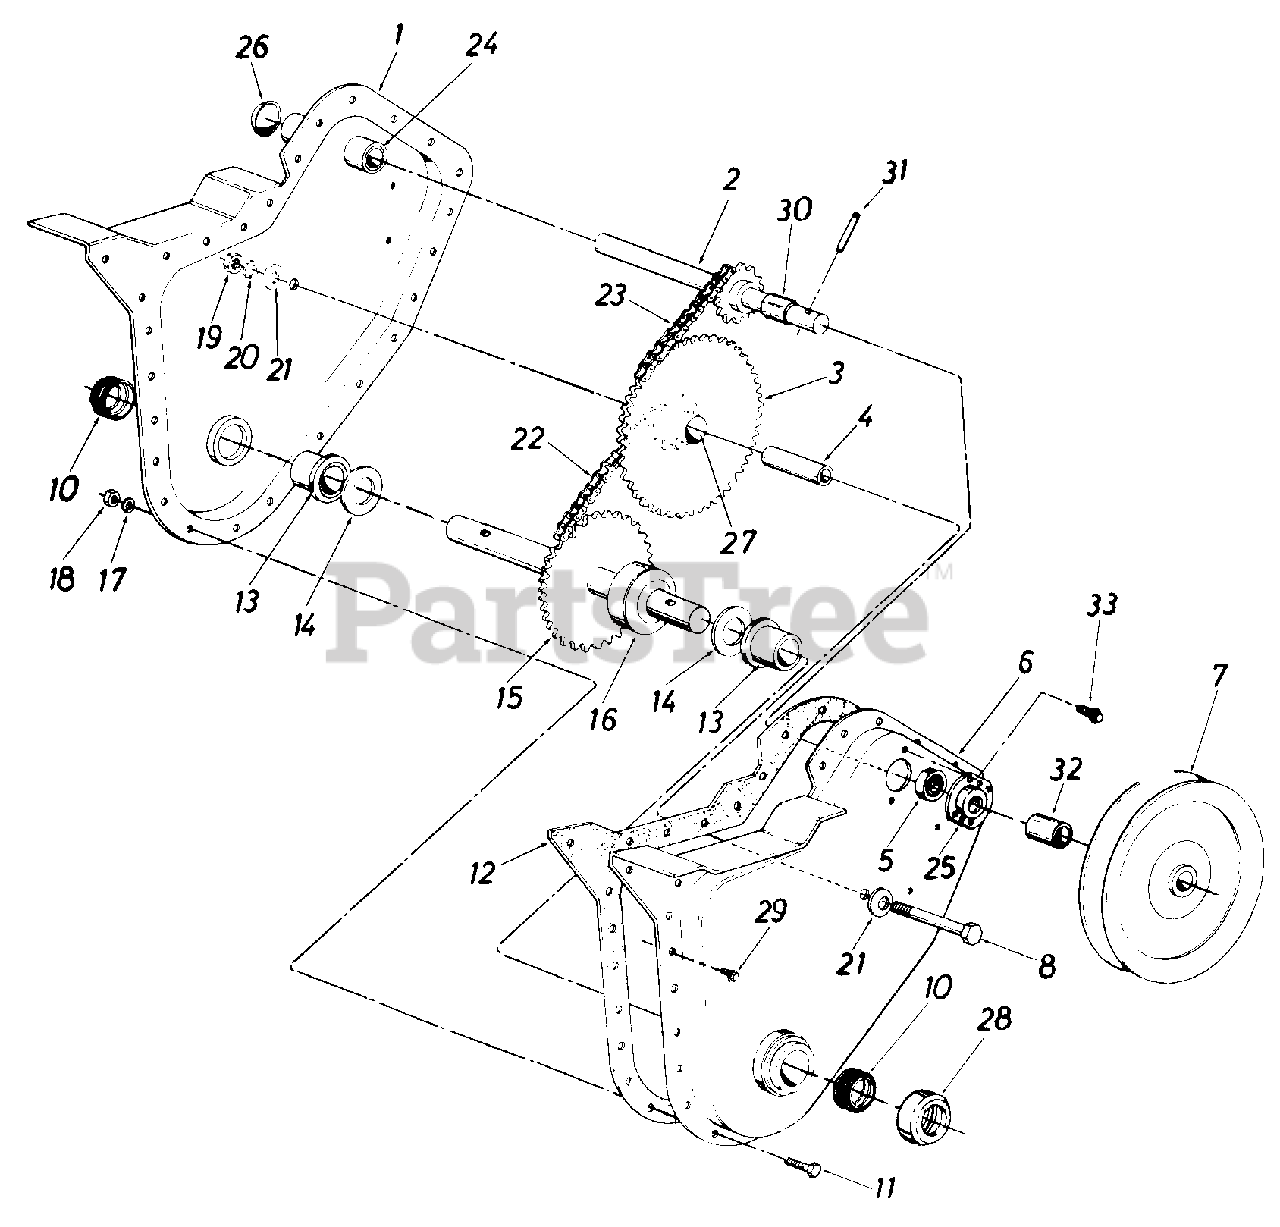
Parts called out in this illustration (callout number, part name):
1	Chain Case Ass'y. R.H.
2	Input Shaft Ass'y.
3	Hub and Sprocket Ass'y.
4	Bearing Inner Race
5	Ball Bearing
6	Chain Case Ass'y. L.H.
7	Pulley Chain Case 51/2 x 1/2
8	Hex Bolt 3/8-24 x 2.50" Lg.
11	Hex Bolt 1/4-28 x .625" Lg.
12	Gasket
13	Flange Brg. .879 I.D.
14	Fl-Wash. .88 I.D. x 1.50 O.D. x .030
15	Tine Shaft Ass'y.
16	Spacer 718" I.D. x .68" Lg.
17	L-Wash. 1/4" I.D.
18	Hex Nut 1/4-28 Thd.
19	Hex Ins. L-Nut 3/8-24 Thd.
20	L-Wash. 3/8" I.D.
21	Bell-Wash. .406 I.D. x 1.130 O.D.
22	Chain #420 .50" Pitch x 38 Links
23	Chain #35 .375" Pitch x 50 Links
24	Bearing .62" I.D. x .813 O.D. x 1.31
25	Bearing Housing
26	Expansion Plug 13/16" Dia.
27	Bearing
28	Dust Cap
29	Hex Wash. Hd. Self-Tap Scr. 1/4-20 x .50" Lg.
30	Spacer .630" I.D. x .77" O.D. x.38" Lg.
31	Spring Pin Spiral 1/4" Dia. x 1-1/2 " Lg.
32	Spacer .647 x 1.25"
33	Hex Wash. Hd. Self-Tap Scr. 1/4-20 x .38" Lg.
